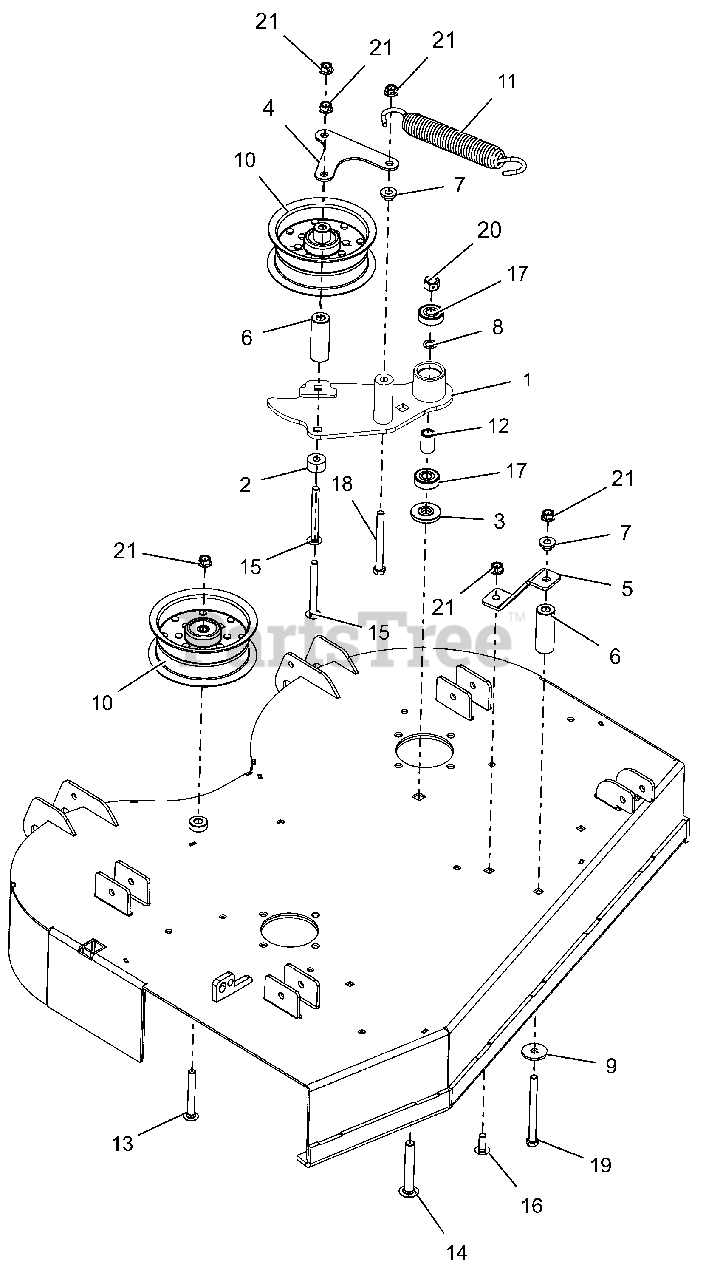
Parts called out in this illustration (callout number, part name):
1	WLDMT, IDLER ARM (BLACK)
2	SPACER .390X1.000X.562
3	SPACER, IDLER ARM
4	BRKT, SUPPORT (BLACK)
5	BRKT, SPRG ANCHOR (BLACK)
6	SPCR, TUBE (BLACK)
7	BSHG-FLG .385X.500X.875X.406
8	WASHER, .500X.750X.020 THRUST
9	WSHR-FL-STL .406X1.375X.135 YZ
10	PULLEY, FLAT 5.00X2.36X.375
11	SPRING, EXTENSION
12	SPACER .510 X .75 X 1.1485
13	@BLT-RDHDSQNK .38-16X3.00 G5YZ
14	BLT,RDHDSQSHNK.50-13X3.25 G5YZ
15	@BLT-RHDSSQNK .38-16X3.50 G5YZ
16	@BLT-RDHDSHSQNK.38-16X1.0 G5YZ
17	BRG-BALL .500X1.38X.437
18	@BLT-HEX .38-16X3.75 GR5 YWZC
19	@BLT-HEX .38-16X4.25 GR5 YWZC
20	@NUT-LK-CTR .50-13 YWZC
21	NUT-LK-CTR-FLG .38-16 YWZC
